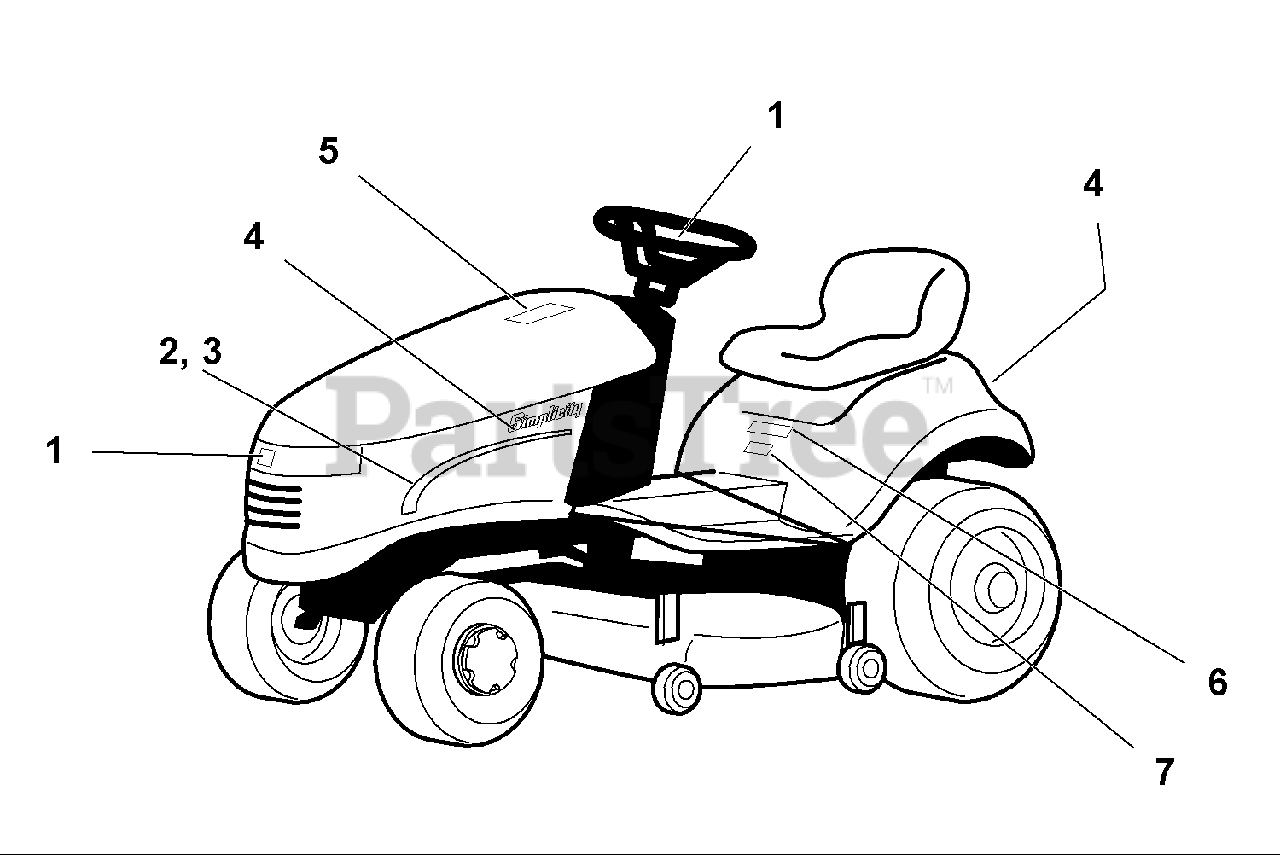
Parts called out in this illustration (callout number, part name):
1	DECAL, Simplicity Icon
2	DECAL, Simplicity Stripe RH
3	DECAL, Simplicity Stripe LH
4	DECAL, Simplicity
5	DECAL, Touch Up Paint
6	DECAL, Silver & Blue
7	DECAL, 15HP
